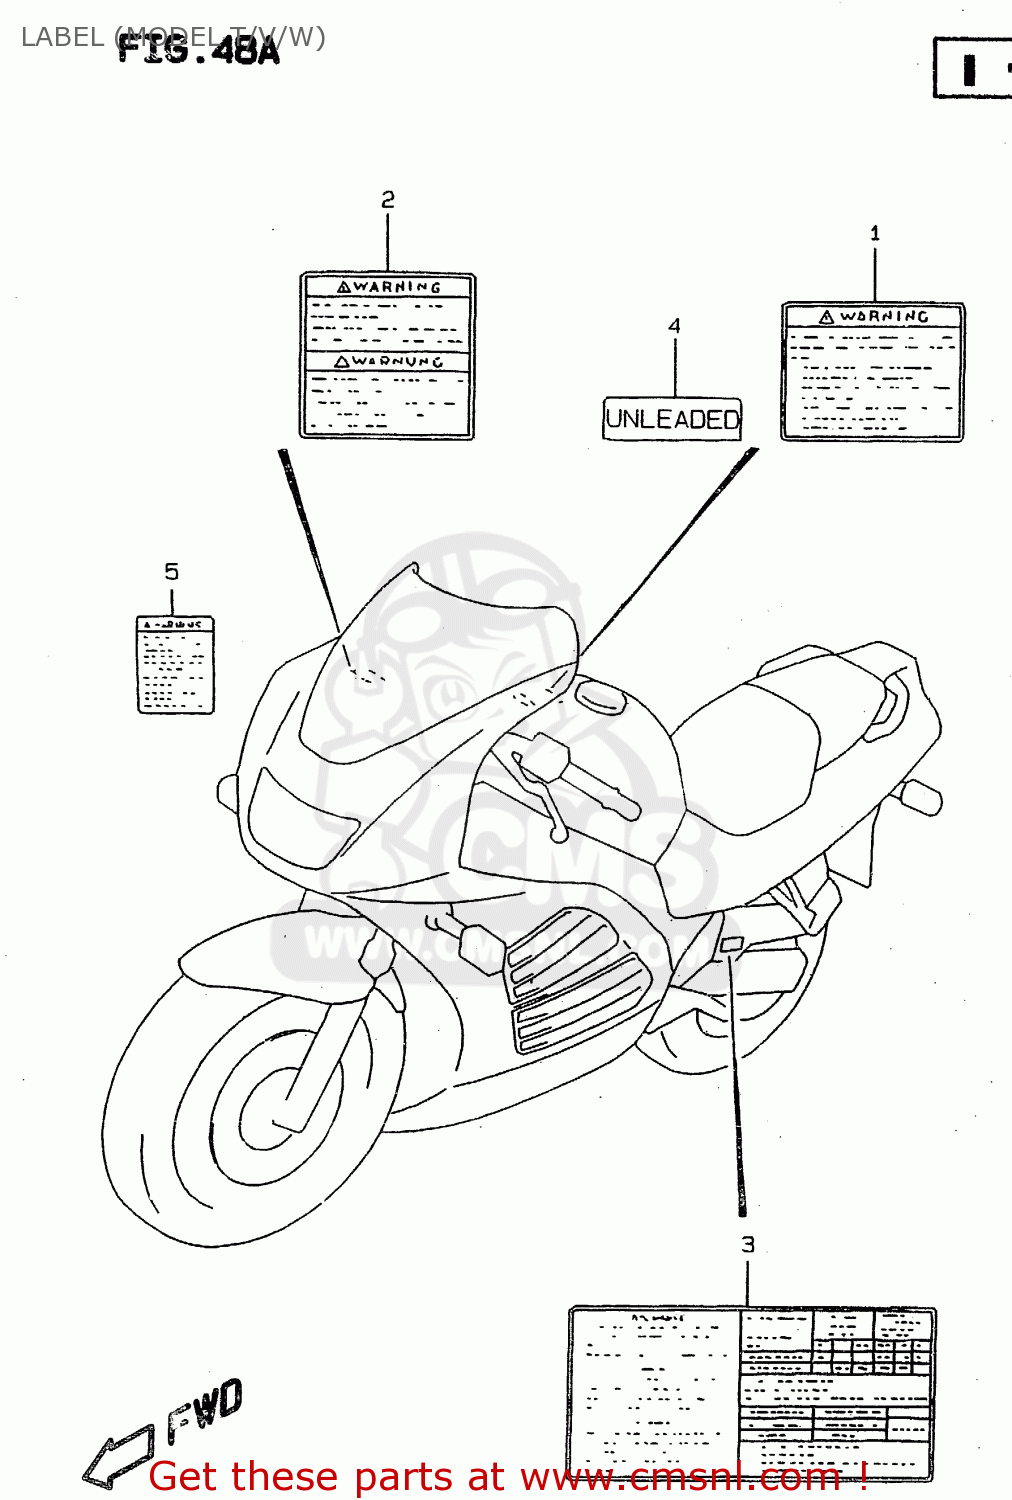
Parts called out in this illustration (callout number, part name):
1	LABEL,WARNING
2	LABEL,WARNING STEERING
3	LABEL, TIRE INFORMATION
4	LABEL,CAUTION
5	LABEL (WARNING SCREEN)
6	MANUAL,OWNER'S
